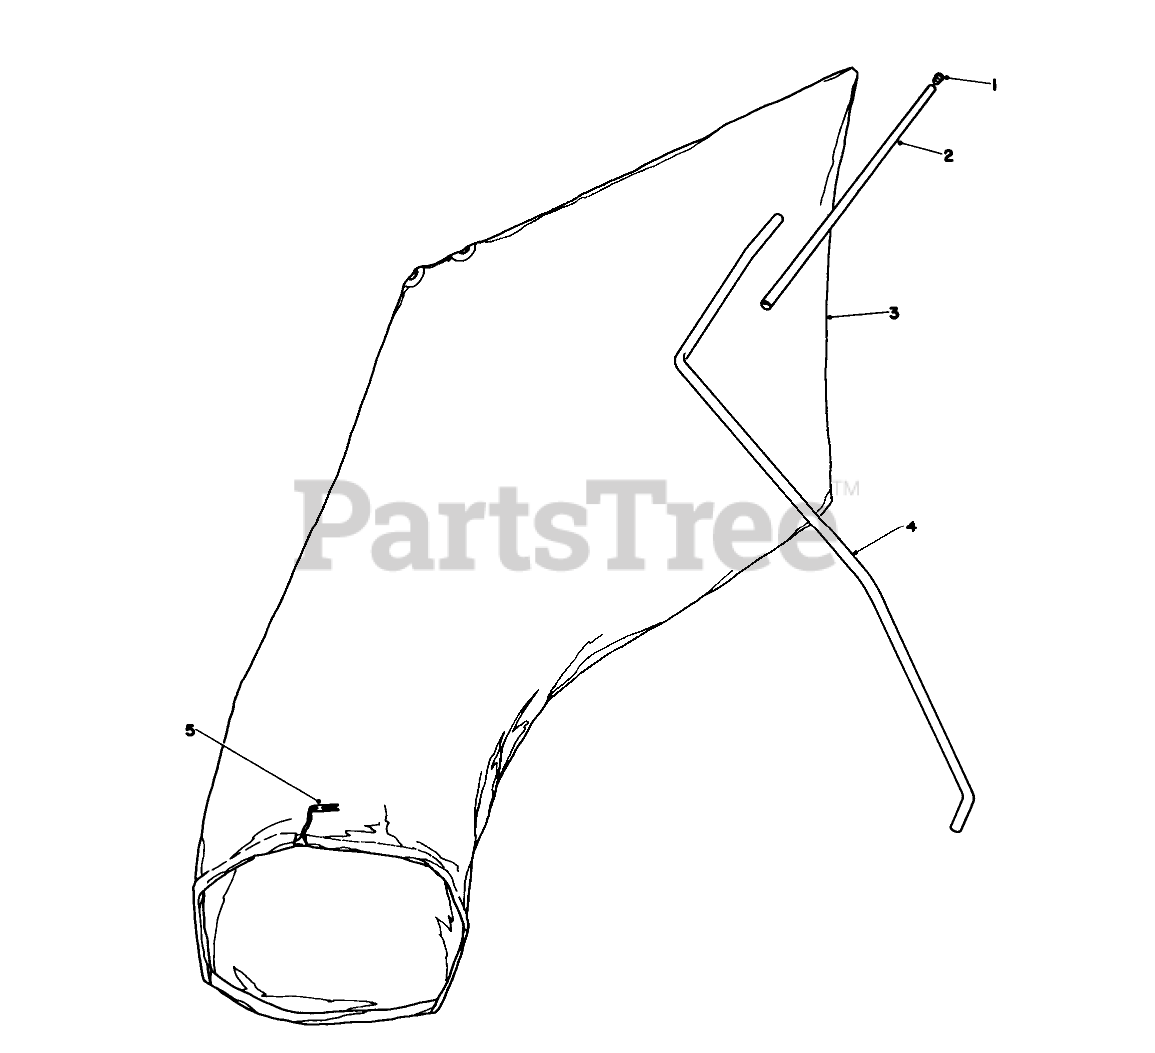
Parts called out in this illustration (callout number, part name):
2	BAG HANGER TUBE
3	Bag (Incl. Ref. #5)
4	HANGER ROD
5	BAG CORD FASTENER
